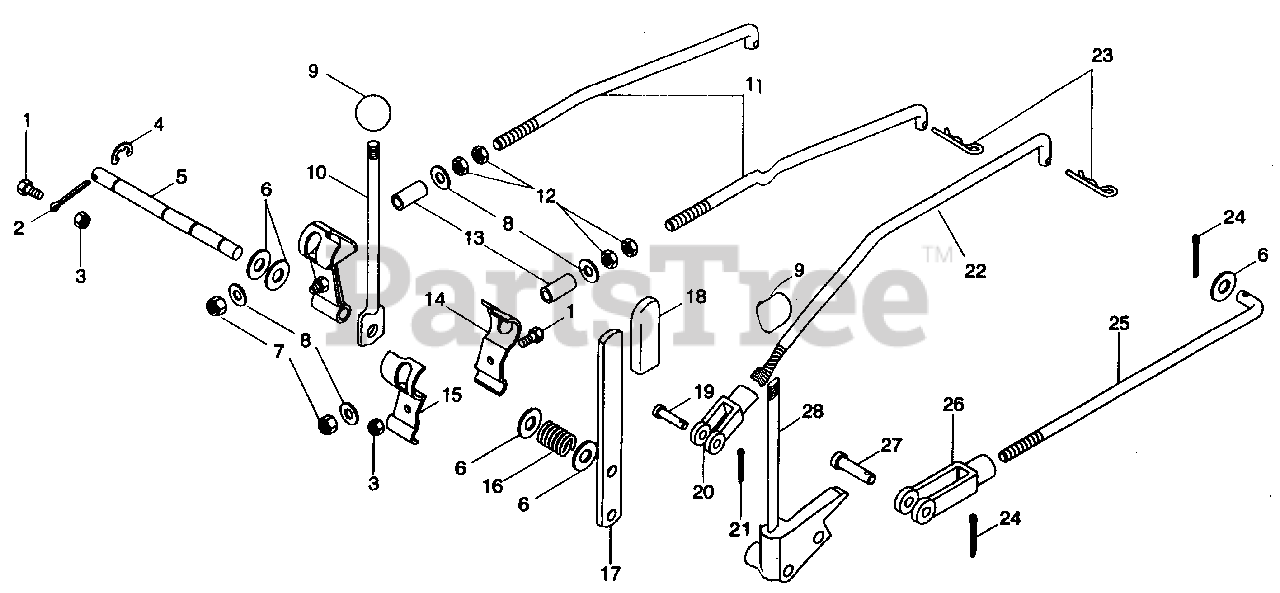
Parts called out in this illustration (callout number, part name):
1	BLT-HEX .31-18 X .75 PL GR 5
2	PIN-COTR .250 X 2.00
3	NUT-LK-NYL .312-18 PL
4	RG-RTNG-EXT .500 X .042
5	CROSS SHAFT
6	WSHR-FL-STL .531 X 1.062 X .095
7	NUT-LK-NYL .375-16 PL
8	WSHR-FL-STL .438 X 1.0 X .083 PL
9	KNOB-CONTROL .438-20 X .50
10	LVR, SHIFT
11	ROD, SHIFT
12	NUT-JAM .375-16 PL
13	BUSH., S .396 X .490 X 1.63 ST
14	ARM, SHIFTER RIGHT
15	ARM, SHIFTER LEFT
16	SG-COMP .085 X .50 X 2.75 WLD 34
17	LVR, HIGH-LOW SHIFT
18	GRIP HANDLE
19	PIN, CLEVIS .500 X 1.213
20	CLVS, .38-24 ADJUSTABLE
21	PIN-COTR .09 X .75 PL
22	ROD, 2-SPEED
23	PIN-HAIR INT .08 X .18 X 1.18
24	PIN-COTR .12 X 1.0 PL
25	ROD, PTO
26	YOKE, .50-20, ADJUSTABLE
27	PIN, CLEVIS; .500 X 1.213
28	ASM, P.T.O. CONTROL
